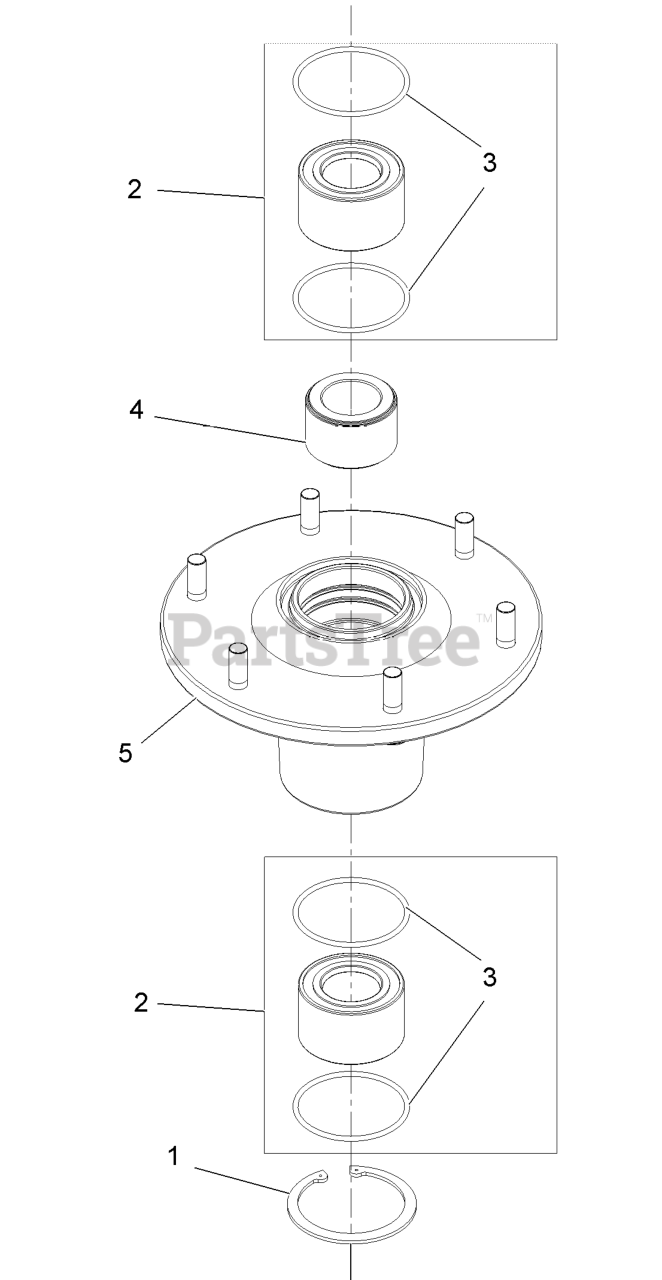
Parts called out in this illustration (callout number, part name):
1	RING-RETAINING
2	ASM, BEARING W/ORINGS
4	SPACER,BEARING
5	ASM,HOUSING W/STUDS
